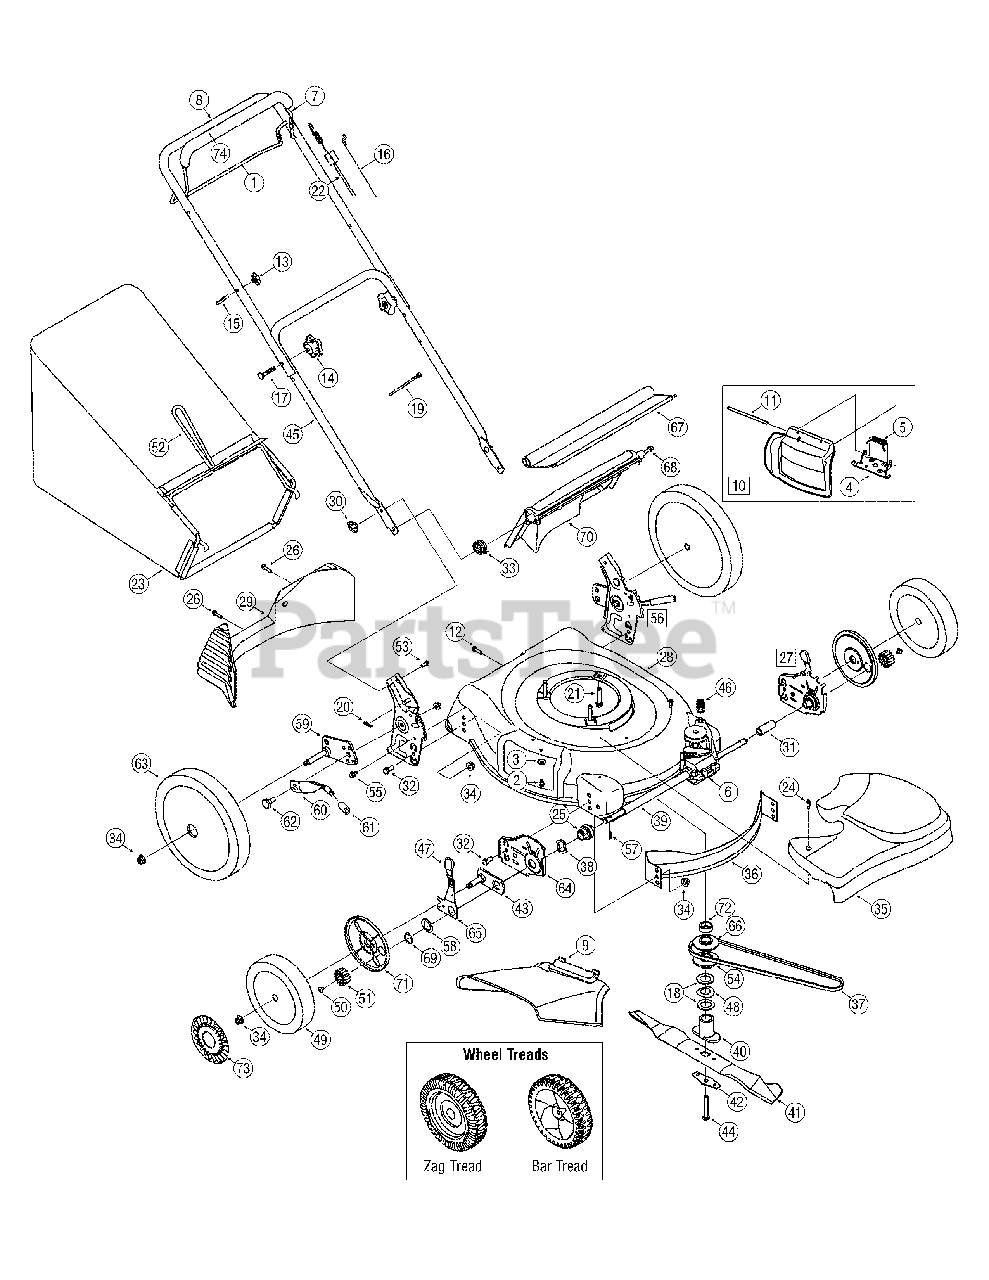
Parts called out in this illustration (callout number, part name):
1	Drive Control
2	TT Screw 1/4-20 x 0.5
3	Bell Washer.265 x 0.75
4	Deflector Chute Adapter
5	Torsion Spring
6	Transmission Assembly
7	Blade Control
9	Chute Deflector
10	Mulch Plug Complete
11	Hinge Pin
12	Screw, Machine, 1/4-20 x .500
13	Handle Knob
14	Star Knob
15	Eye Bolt
16	Control Cable - 37.750"
17	Carriage Bolt 5/16-18 x 2.0
18	Washer, Flat, 1.00 x 1.25 x .107
19	Cable Tie
20	Cotter Pin
21	Self-Tapping Sems Screw
22	Drive Cable - 51"
23	Grassbag Assembly
24	Shoulder Screw # 12 -24
25	Front Bearing Assembly
26	Screw, 1/4-15 x 1.000
27	Height Adjustment Ass’y - RH
27	Height Adjustment Ass’y - LH
30	Wing Nut
31	Slev. Spacer 1.4" Lg.
32	Hex Screw, 3/8-16 x.75
33	Torsion Spring - RH
34	Flange Lock Nut, 3/8-16
35	Transmission Cover - Black
35	Transmission Cover - Yellow
36	Front Baffle
37	V-Belt
38	Wave Washer
39	Sleeve Spacer 8.985" Lg.
40	Blade Adapter
41	21" Mulching Blade
42	Blade Bell Support
43	Pivot Plate Assembly
44	Hex Screw 3/8-24 x 2.50
45	Lower Handle
46	Belt Tension Spring
47	Adjustment Knob
48	Wash, Sprg, 1.005 x 1.825 x .048
49	Front Wheel, 8 x 1.8, Bar, Gray
49	Front Wheel, 8 x 1.8, Bar, Yellow
50	Screw, 1/4-20 x .390
51	Gear 14T RH FWD
51	Gear 14T LH FWD
53	Carriage Bolt 1/4-20
54	Pulley, Half
55	TT Scr. w/Washer 1/4-20 x.625
56	Handle Bracket Assembly - LH
56	Handle Bracket Assembly - RH
57	Dowel Pin
58	Washer
59	Pivot Arm Assembly - RH
59	Pivot Arm Assembly - LH
60	Rear Spring Lever
61	Foam Grip
62	Shoulder Scr.500 Dia. x.434
63	Rear Wheel, 12 x 1.8, Bar, Gray
63	Rear Wheel, 12 x 1.8, Bar, Yellow
64	Height Adjuster Plate - RH
64	Height Adjuster Plate - LH
65	Front Lever - RH
65	Front Lever - LH
66	Pulley, Half
67	Rear Trailing Shield
68	Pivot Rod
69	Snap Ring
70	Rear Discharge Door
71	Wheel Dust Cap
72	Spcr, Slev, 25mm x 1.375 x .620
73	Hub Cap
74	Deluxe Bail Cover
